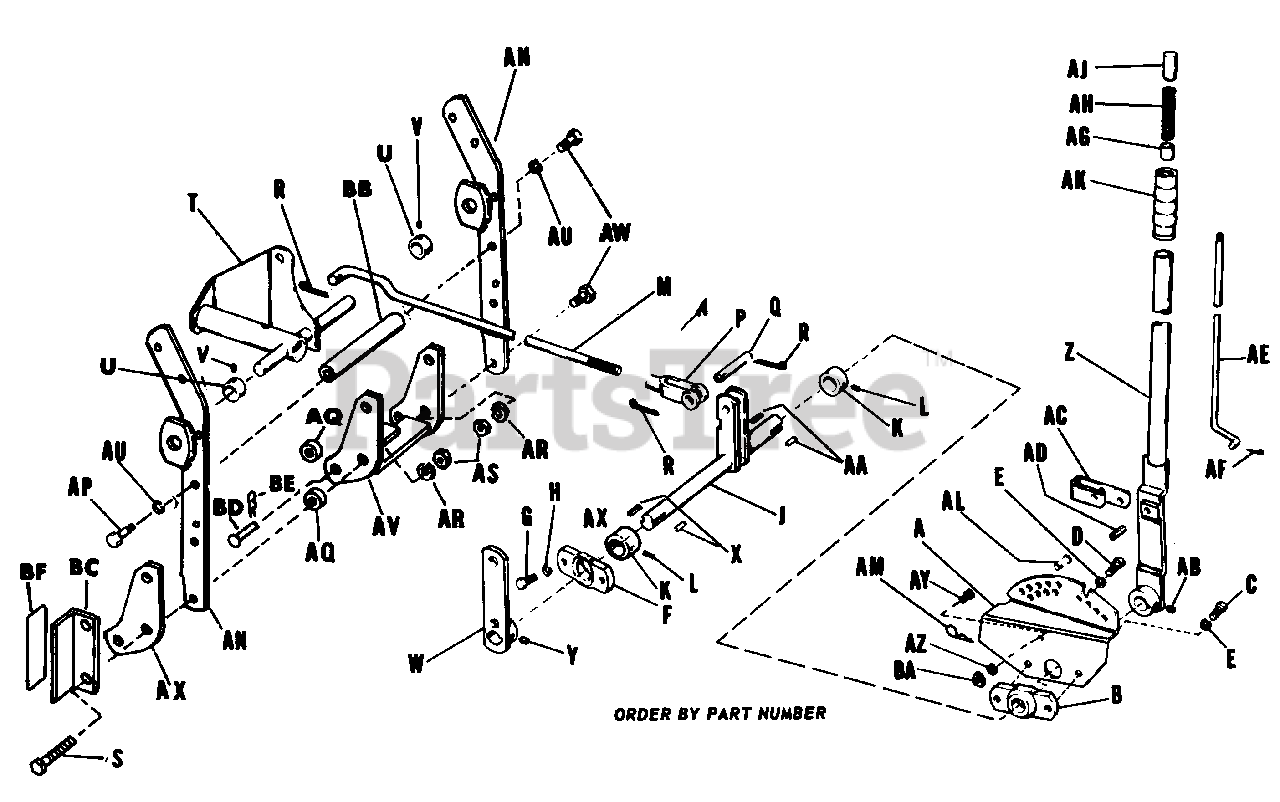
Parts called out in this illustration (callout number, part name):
A	Lift Lever Quadrant
B	Lift Lever Bearing
C	Hex. Cap Screw, 3/8"-16 x 7/8"
D	Hex. Cap Screw, 3/8"-16 x 1-1/4"
E	Lock Washer, 3/8"
F	Lift Lever Bearing
G	Hex. Cap Screw, 3/8"-16 x 7/8"
H	I, ock Washer, 3/8"
J	Lift Shaft .Assembly
K	Set Collar
L	Set Screw 5/16"-18 x 5/16"
M	Rear Lift Rod
P	Adj. Yoke End
R	Cotter Pin, 1/8" x 1"
S	Hex. Cap Screw, 7/16"-14 x 2-1/2"
T	Tiller Lift.Assembly
U	Set Collar
V	Set Screw, 5/16"-18 x 5/16"
W	Front Lift Lever Assembly
Y	Set Screw, 5/16"-18 x 1/4"
Z	Lift Lever Assembly
AB	Set Screw, 5/16"-18 x 1/4"
AC	Lift Lever Latch
AE	Latch Rod
AF	Cotter Pin, 3/32" x 3/4"
AJ	Thumb Button
AK	Handle Grip
AM	Spring Clip
AN	Arm Assembly
AP	Hex. Capscrew, 7/16"-14 x 1-3/4
AR	Lock Washer, 3/8"
AS	Full Hex. Nut, 7/16"
AT	Hex. Cap Screw, 7/16"-14 x 1"
AU	Lock Washer, 7/16"
AV	Draw Bar Assembly
AW	Hex. Cap Screw, 7/16"-14 x 1-1/4'
AY	Hex Cap Screw, 1/4-20 x 5/8" lg.
AZ	Lock Washer, 1/4"
BA	Hex Nut, 1/4-20
BC	Plate, Decal
BD	Round Head Pin
BE	Spring Clip
BF	Film, Safety
